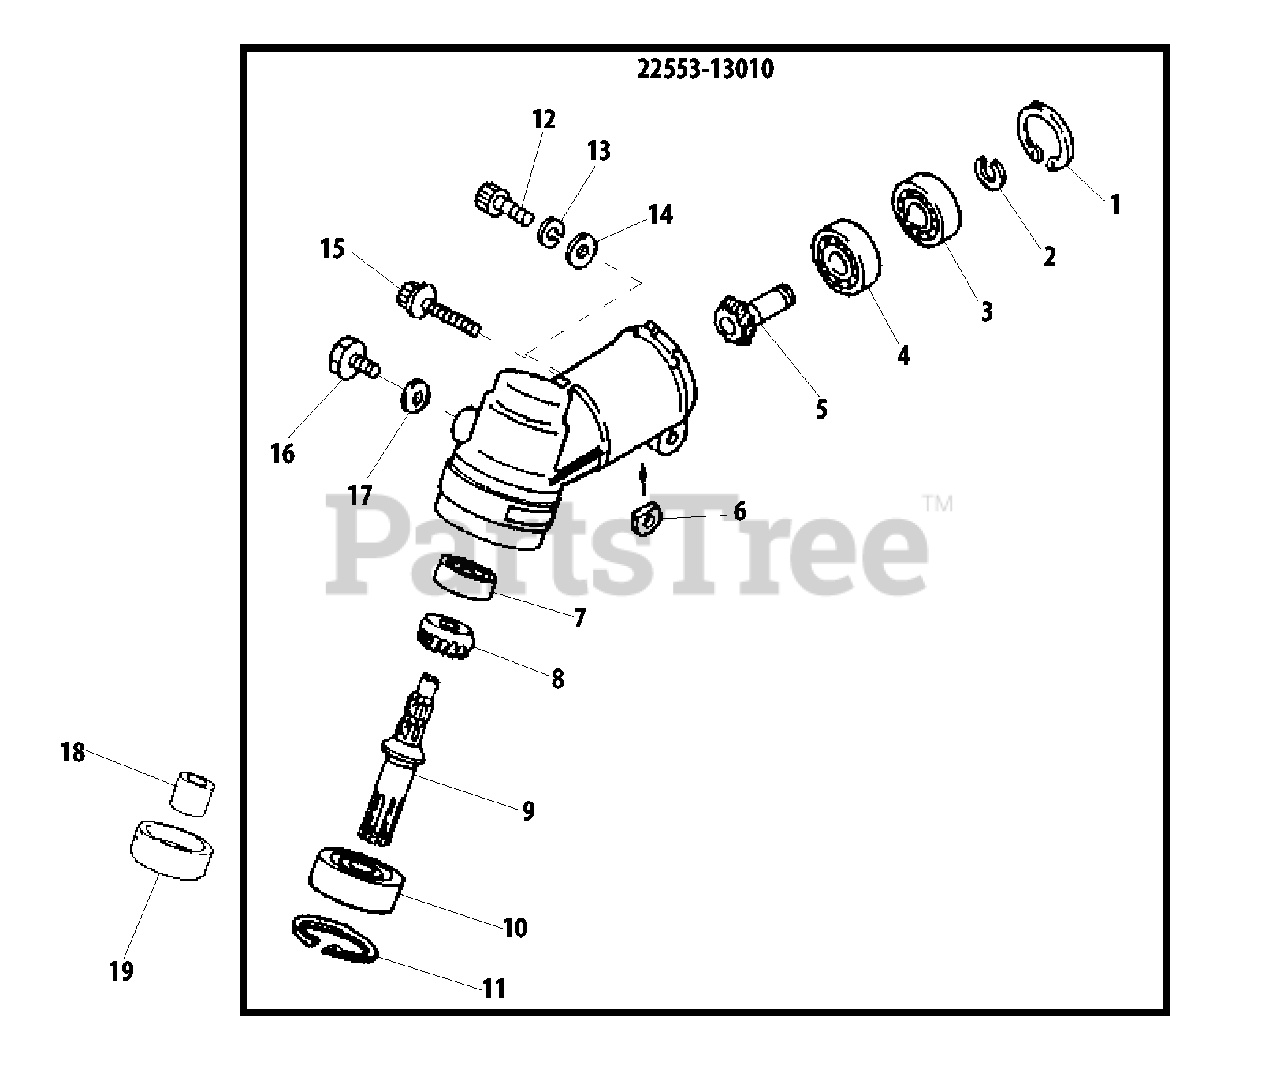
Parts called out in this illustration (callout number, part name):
1	RING, RETAINING - 22
2	RING, RETAINING
3	BEARING, BALL - 608ZZ
4	BEARING, BALL - 608
5	GEAR - PINION
6	SHIM
7	BEARING, BALL - 626
8	GEAR - BEVEL
9	GEAR - SHAFT
10	BEARING, BALL - 6000DDU
11	RING, RETAINING - 26
12	SCREW - 5X12
13	LOCKWASHER - 5
14	WASHER - 5
15	SCREW - 5X25
16	BOLT - 6X10
17	WASHER
18	COLLAR
19	HOLDER
22553-13010	GEAR CASE ASSY
